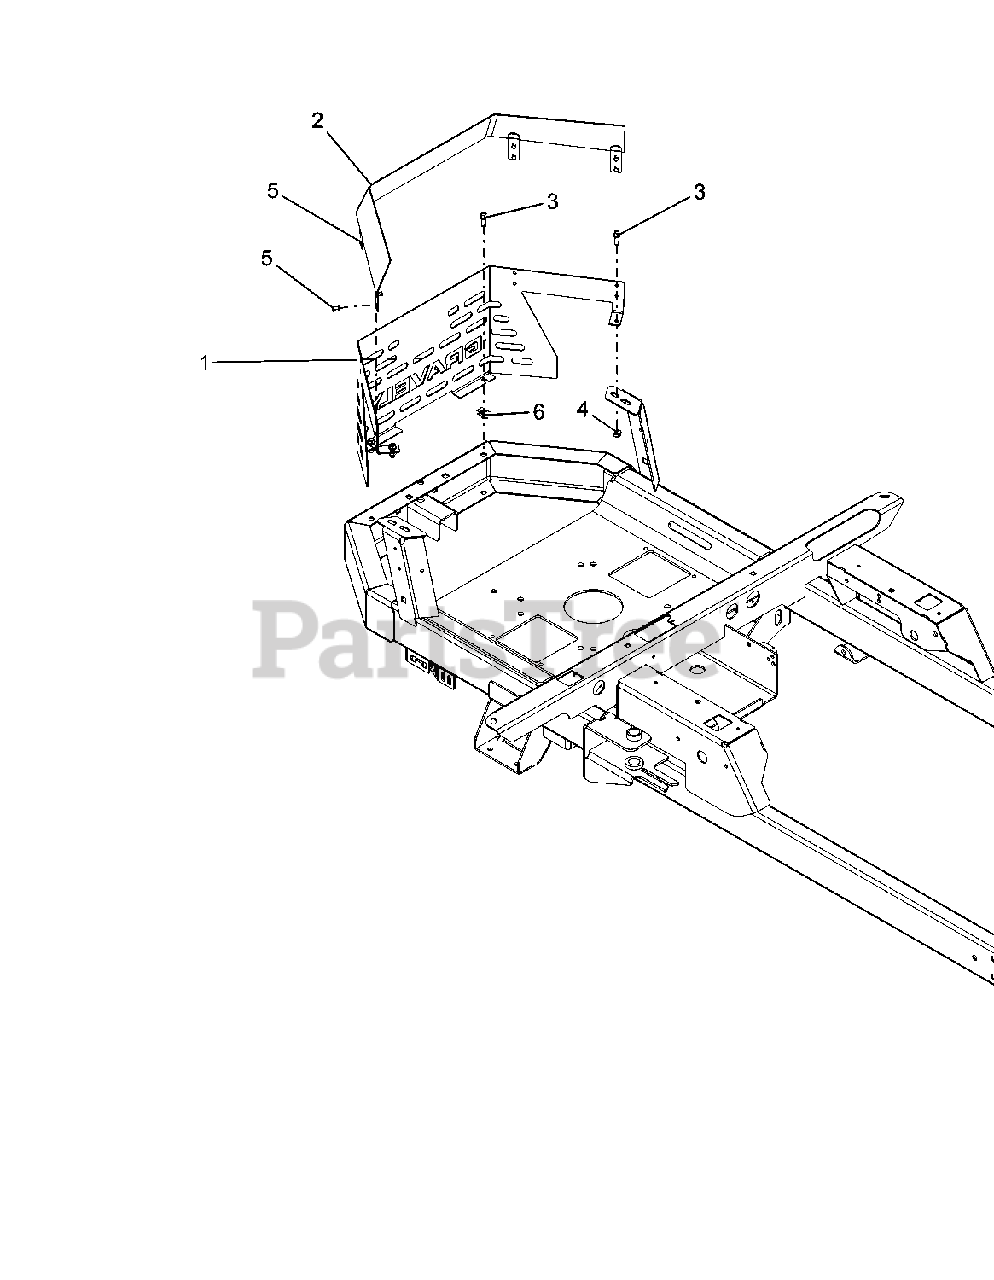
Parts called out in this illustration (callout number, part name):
1	SHROUD, ENGINE GRAVELY
2	WLDMT, ENGINE SHROUD TOP TRIM
3	BLT-HEX .25-20X.75 HWH YWZC GR5
4	NUT, LK-TOP-FLG .25-20 YWZC
5	RVT-POP .187x.375 (#66) BLACK
6	NUT, RTNR .25-20 X .56
